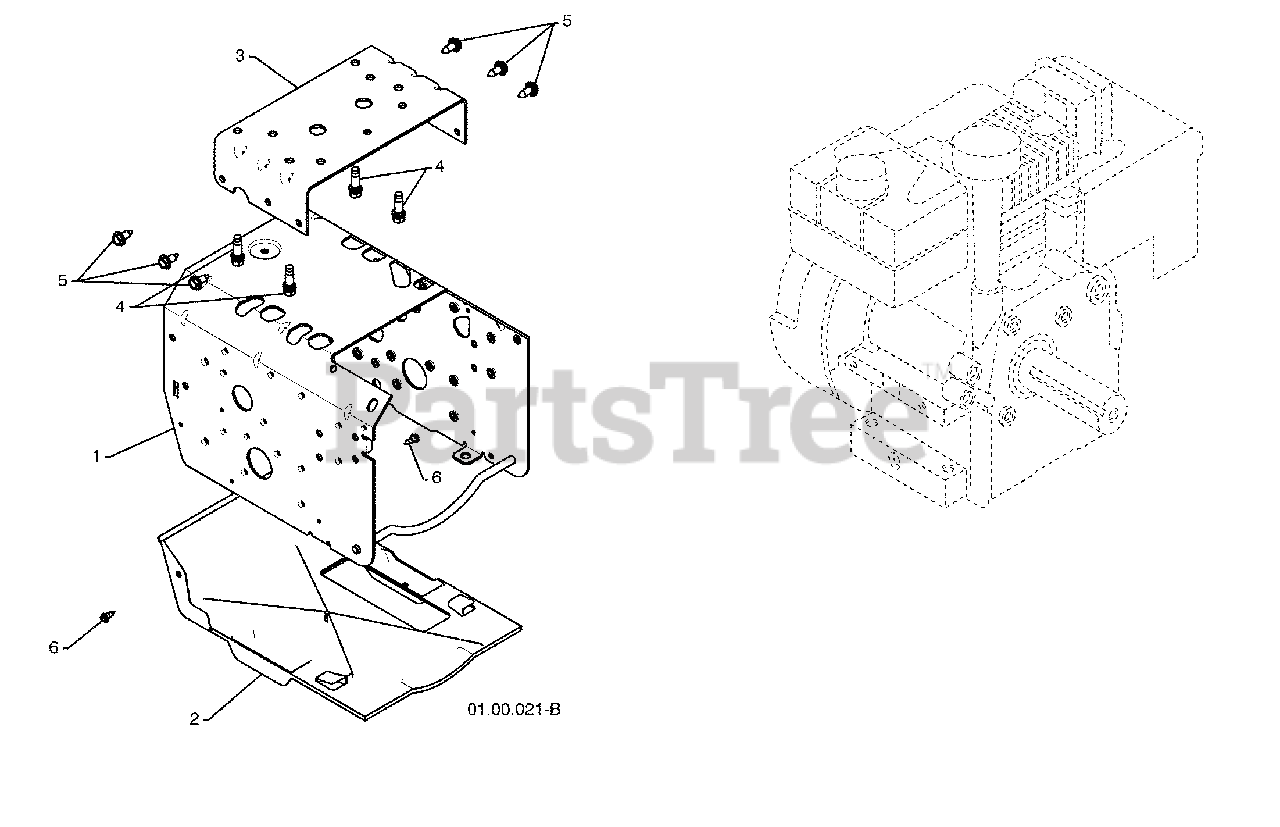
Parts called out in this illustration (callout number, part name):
2	BOTTOM PAN
3	ENGINE MOUNT PLATE
4	BOLT 3/8-16
5	SCREW 5/16-18 X .750
6	SCREW 10-24 X .625
